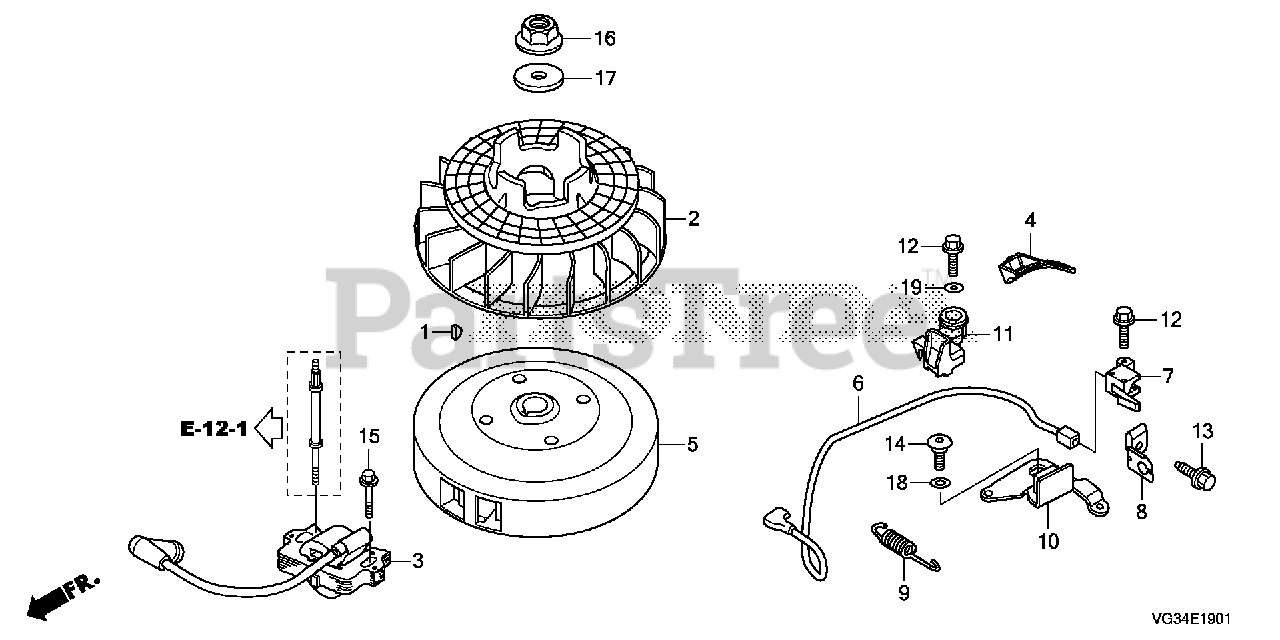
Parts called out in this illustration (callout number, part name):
1	KEY, SPECIAL WOODRUFF (25X18)
2	FAN, COOLING
3	COIL ASSY., IGNITION (PHELON)
3	COIL ASSY., IGN
4	CLAMP, WIRE
5	FLYWHEEL (FENGLONG)
5	FLYWHEEL (PHELON) (NA USE ALT:31110-Z8B-901)
6	WIRE, STOP SWITCH
7	SWITCH ASSY., ENGINE STOP
8	BRACKET, BRAKE CABLE
9	SPRING, BRAKE LEVER
10	ARM, BRAKE
11	SPRING, TENSIONER
12	BOLT, SPECIAL (5X16)
13	BOLT, FLANGE (6X14)
14	BOLT, SPECIAL
15	BOLT, FLANGE (6X23)
16	NUT, SPECIAL (14MM)
17	WASHER (14X45)
18	WASHER, SPECIAL
19	WASHER, PLAIN (5MM)
